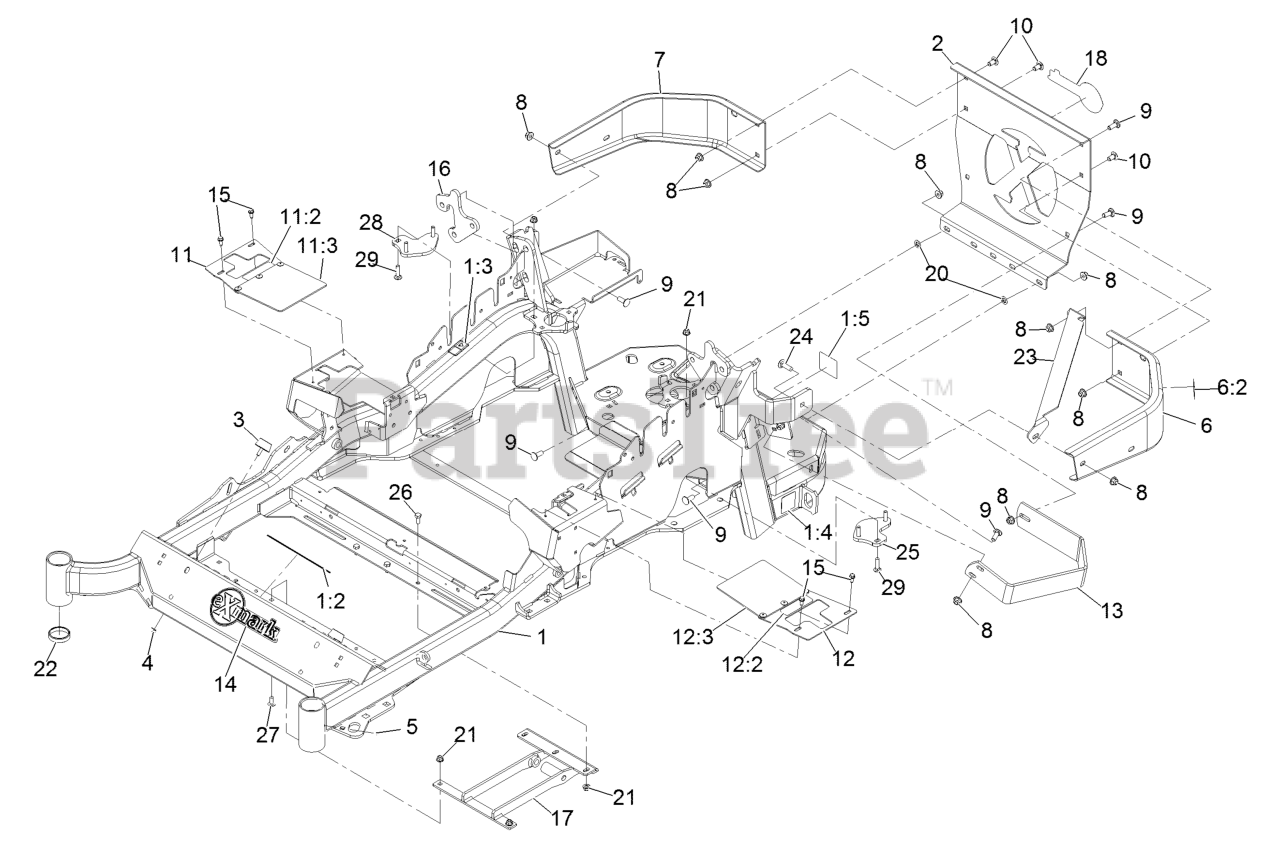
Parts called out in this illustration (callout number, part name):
1	Mainframe ASM
1:2	Decal-Danger
1:3	Decal-Warning
1:4	Decal-Hazard, Pinched Finger
1:5	Decal-Spark Arrester
2	Plate,Rear Guard
4	Nut-Nyloc 1/4-20 Flg
6	LH Bumper ASM
6:2	Decal-Warning
7	Bumper-RH
8	Nut-Nyloc 3/8-16 Flg
9	Bolt-Carriage 3/8-16 X 1
10	Bolt-Carriage 3/8-16 X 3/4
11	RH Motion Control Cover ASM
11:2	Decal-Control, Motion
11:3	Flap-Rubber
12	LH Motion Control Cover ASM
12:2	Decal-Control, Motion
12:3	Flap-Rubber
13	Guard-Muffler
14	Decal-Exmark
15	Screw-HWH 1/4-20 X .62
16	Plate-Mount, Shock
17	Mount-Lower
18	Decal-Exmark Logo
20	Nut-Push 3/8-16
21	Nut-Nyloc 5/16-18 Flg
22	Cup-Bearing Tapered Roller
24	Bolt-Carriage 3/8-16 X 1 1/4
25	LH Plate ASM (W/Studs)
26	Screw-HH 5/16-18 X 3/4
27	Bolt-Carriage 5/16-18 X 3/4 Short Neck
28	RH Plate ASM (W/Studs)
29	Bolt-Carriage 5/16-18 X 1 1/4
